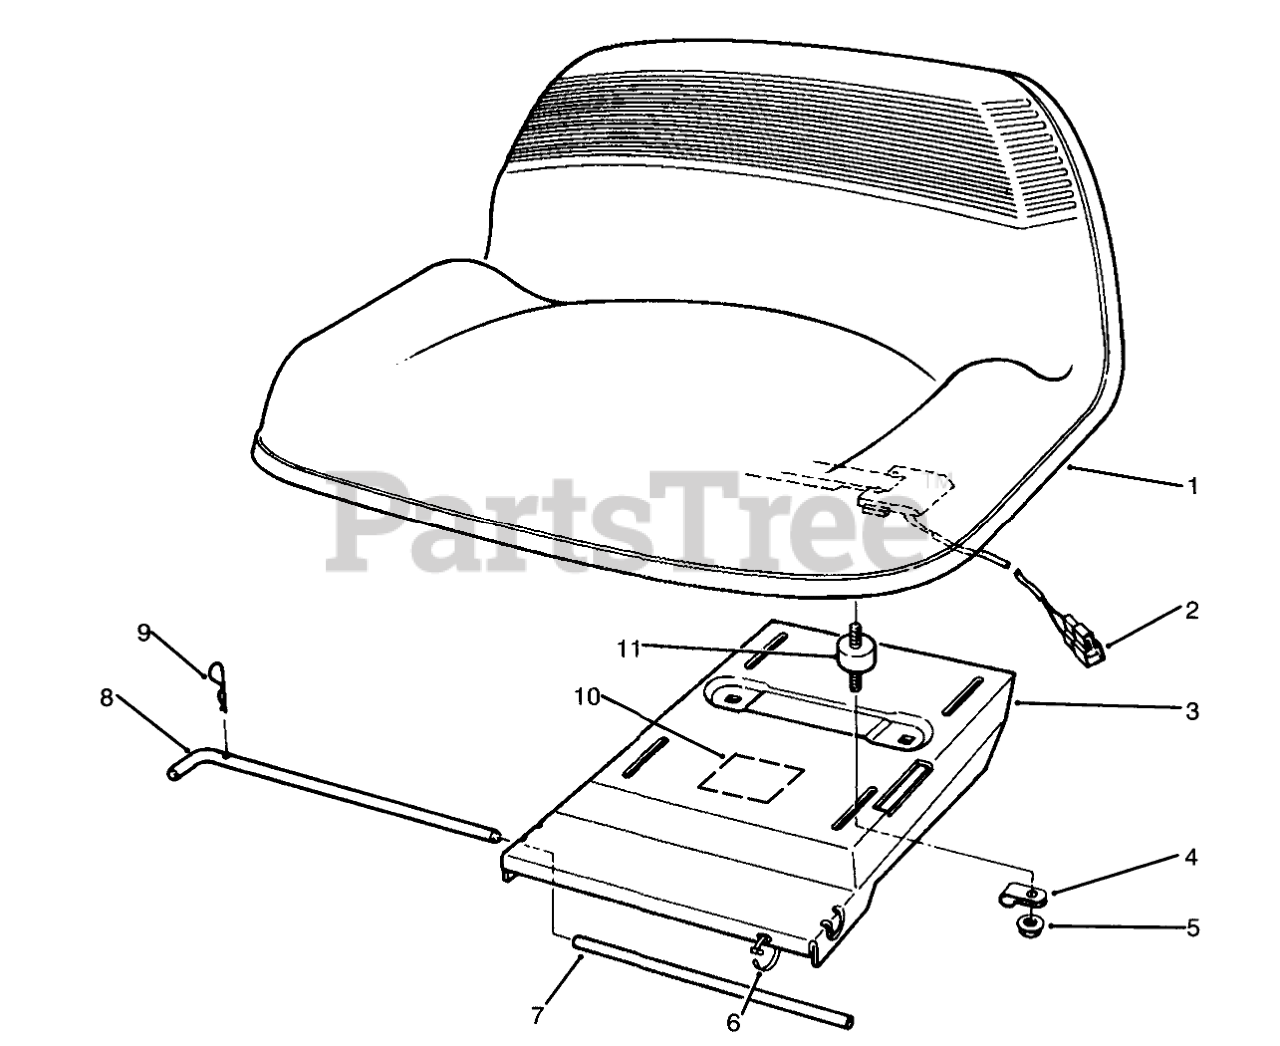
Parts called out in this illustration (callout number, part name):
1	Seat
2	SWITCH-SEAT
3	Base-Seat
4	CLAMP
5	NUT-HF
6	TIE-CABLE
7	TUBE-SEAT
8	ROD-SEAT BASE
9	PIN-COTTER
10	Decal-Noise
11	ISOLATER-SEAT
